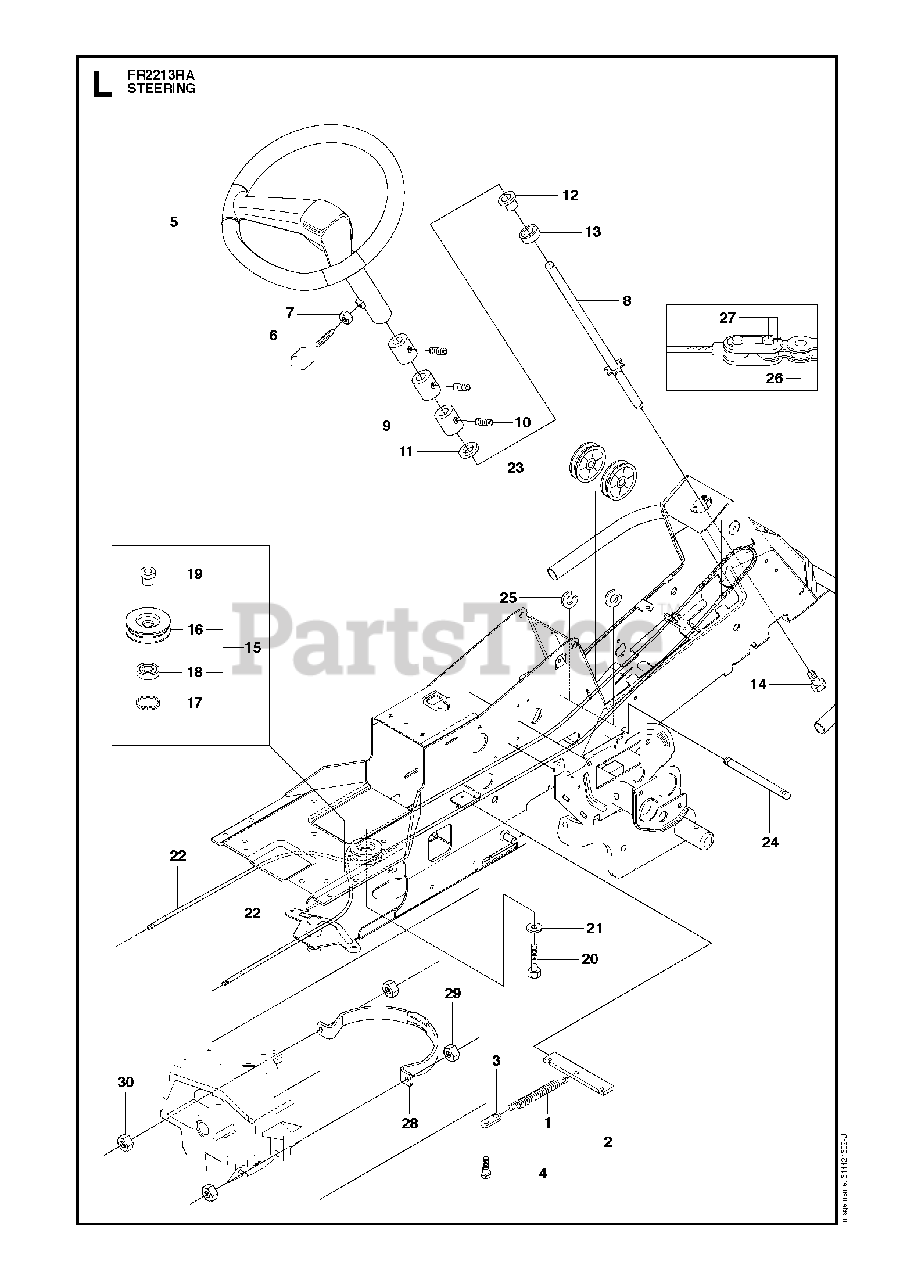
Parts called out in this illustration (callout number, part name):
2	SPRING BRACKET
3	CONNECTOR
5	STEERING WHEEL
7	NUT
8	ROD STEERING ASSY
13	BALL BEARING 6004-2RS1
15	PULLEY
16	ROLLER
17	CIRCLIP SGH 47
18	BALL-BEARING 6204-2RS
19	BUSHING
20	COLLAR SCREW
22	RP STEERING CABLE COMPLETE
25	RETAINING RING
26	STEERING CHAIN
28	WIRE GUIDE
